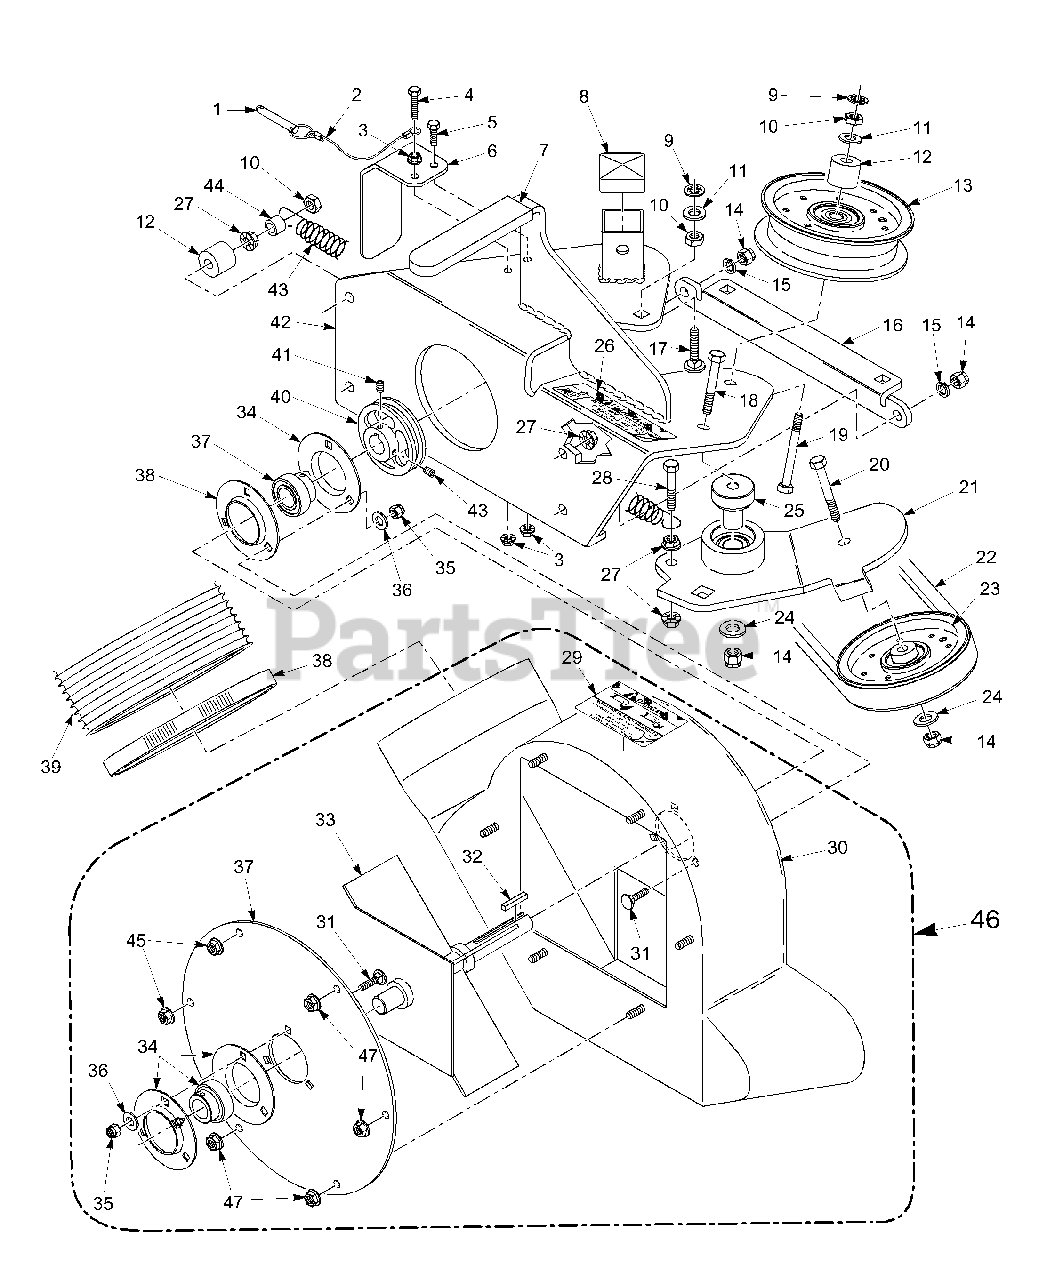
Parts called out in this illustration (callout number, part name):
1	Pin, Ring 2-1/4" Long
2	Lanyard, Deck Height Pin
3	Nut, Serr. Flange 1/4-20
4	Bolt, Hex Head 1/4-20 x 1-1/4"
5	Bolt, Hex Head 1/4-20 x 3/4"
6	Belt Cover, Rear
7	Grip, Blower Lever
8	Cap, Square
9	Nut, Push On 3/8 Thread
10	Lock Nut, 3/8-16
11	Flatwasher, 3/8-.391 x .938 x .105
12	Spacer
13	Pulley, Idler 4" Dia.
14	Nut, Elastic Stop 3/8-16
15	Lockwasher, 3/8-16
16	Plate, Catch Mounting
17	Bolt, Carr. 3/8-16 x 1-1/2"
18	Bolt, Hex Head 3/8-16 x 2-1/4"
19	Bolt, Hex Head 3/8-16 x 3-1/4"
20	Bolt, Hex Head 3/8-16 x 2"
21	Idler Arm Weldment
22	Belt, GC-STC
23	Pulley, 4" O.D.
24	Washer, 3/8 Hardened
25	Pivot, Idler
26	Decal, Belt Cover
27	Nut, Serr. Flange 3/8-16
28	Bolt, Hex Head 3/8-16 x 1-1/2 Gr. 8
29	Decal, Danger
30	Blower Housing Weldment
31	Bolt, Carr. 5/16-18 x 3/4" Gr. 5
32	Key, 1/4 x 1/4 x 1-1/2"
33	Fan Weldment
34	Bearing with Locking Collar
35	Nut, Elastic Stop 5/16-18
36	Flatwasher, 5/16-.344 x .688 x .065
37	Cover, Blower Housing
38	Clamp, 6-1/2" Max Dia.
39	Hose, 6" Dia.
40	Pulley, 4-3/4" O.D. - 1" Bore
41	Set Screw, 5/16-18 x 3/8"
42	Frame Weldment, Blower Mount
43	Spring, Main Drive
44	Spacer
45	Nut, Serr. Flange 5/16-18
46	Blower Housing Assembly
